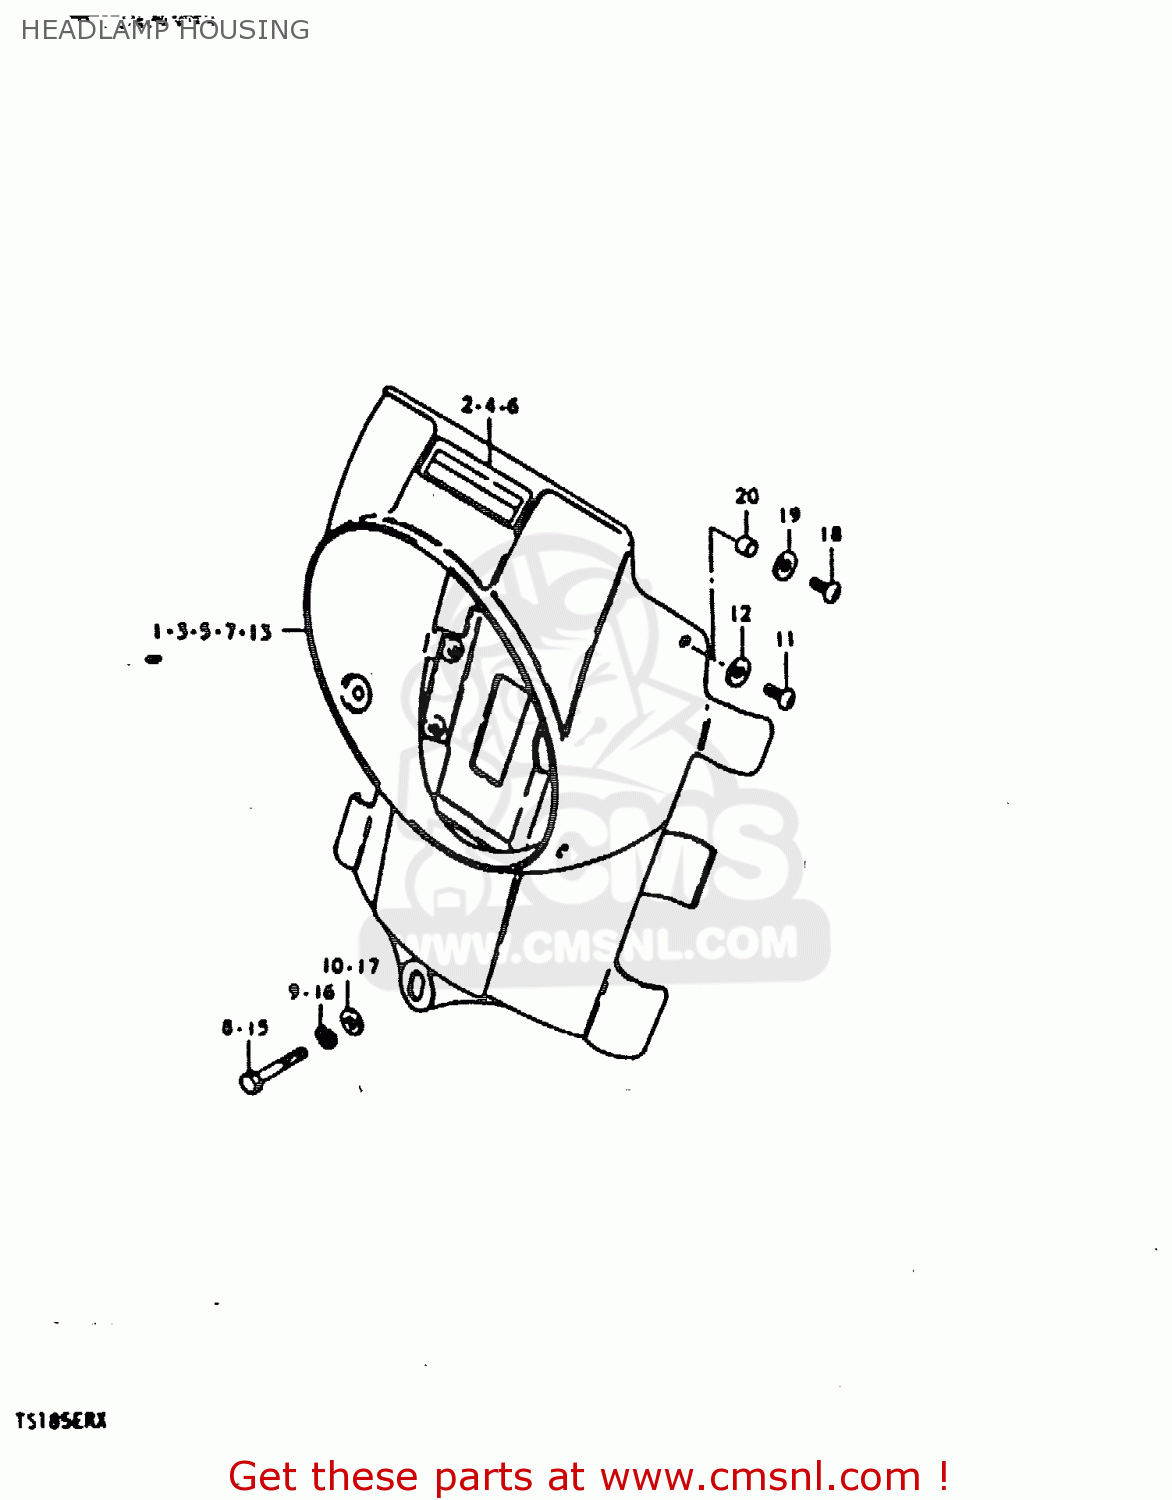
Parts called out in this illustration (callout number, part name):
1	HOUSING, HEADLAMP (RED)
2	TAPE, HOUSING
3	HOUSING,HEADLAMP
4	TAPE, HOUSING
5	HOUSING, HEADLAMP (GREEN)
6	TAPE, HOUSING
8	BOLT
9	LOCK WASHER
10	WASHER
11	SCREW
12	WASHER (5.5X16X1.2)
13	HOUSING,HEADLAMP
14	BOLT
15	LOCK WASHER
16	WASHER
17	SCREW
18	WASHER (5.5X18X1.6)
19	SPACER (5.5X8X4)
